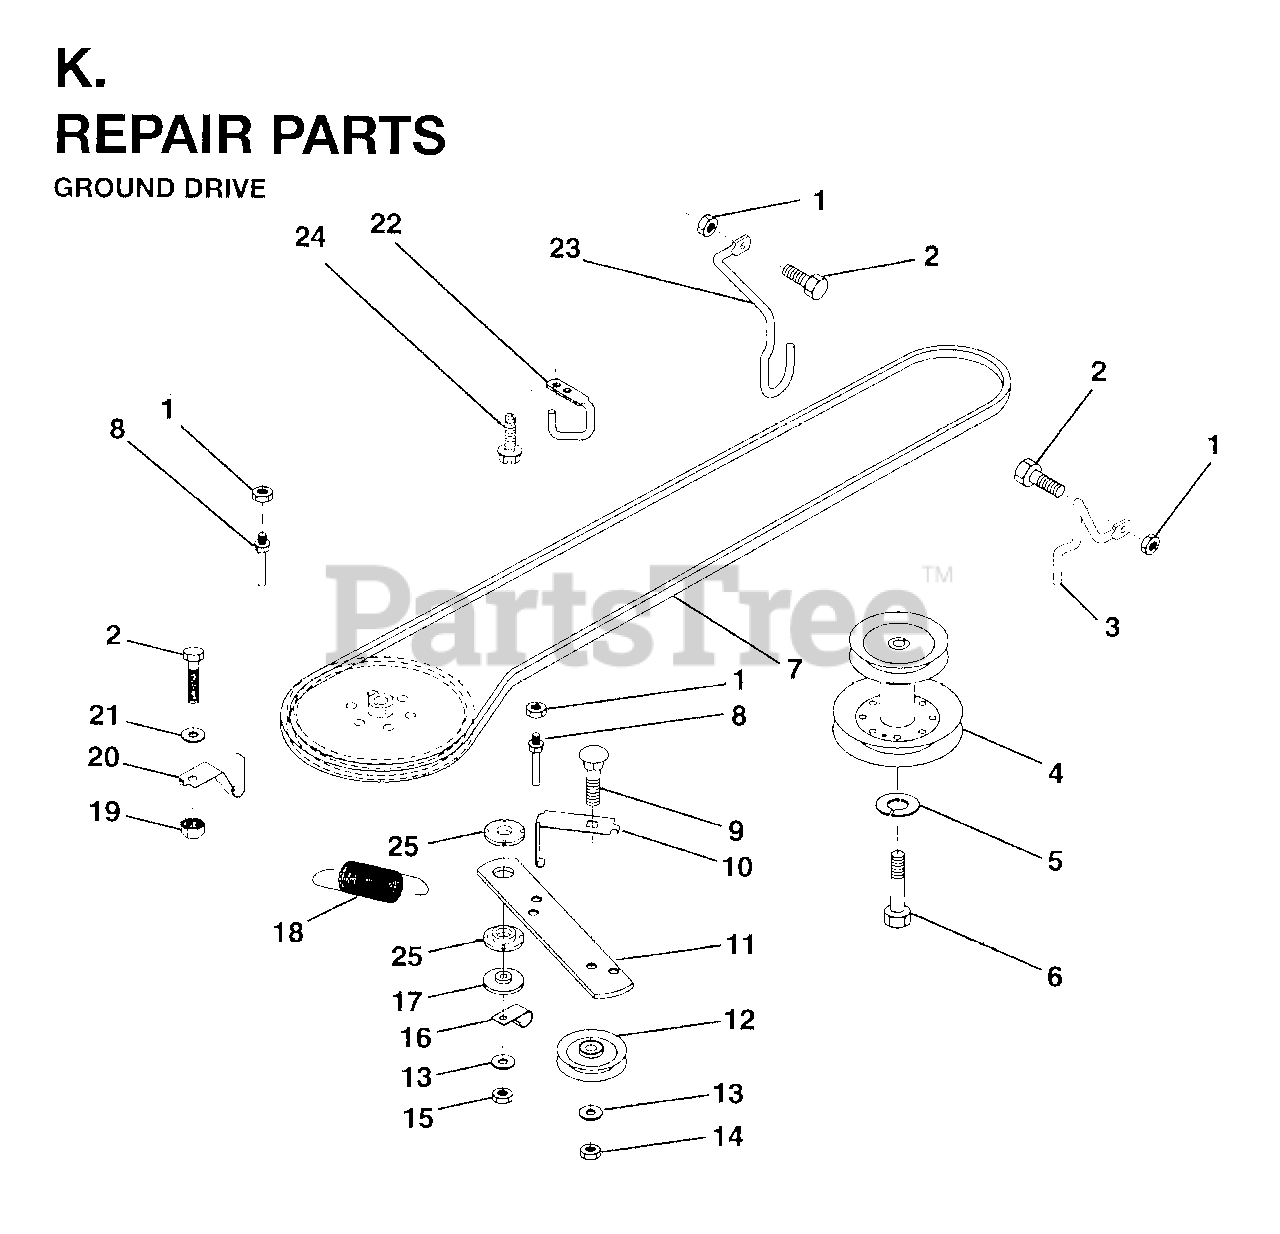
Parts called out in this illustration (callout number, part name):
1	LOCKNUT
2	BOLT
3	KEEPER-MOWER DRIVE LH
4	ENGINE PULLEY
5	LOCKWASHER
7	BELT
8	KEEPER,DRIVE BELT
10	KEEPER.BELT.GROUND.DRIVE.IDLER
11	ARM, GROUND DRIVE CLUTCH
12	PULLEY.IDLER.FLAT
13	WASHER
14	LOCKNUT
15	LOCKNUT
16	CLIP,INSULATOR
17	SPACER, RETAINER
18	SPRING.EXTENSION
19	LOCKNUT
20	KEEPER-T/A GROUND DRIVE BELT
21	WASHER - 15X7.3X1.6
22	KEEPER,FRA DR BEL
23	KEEPER/MOWER DRIVE RH
25	BUSHING NYLON COLLERED
